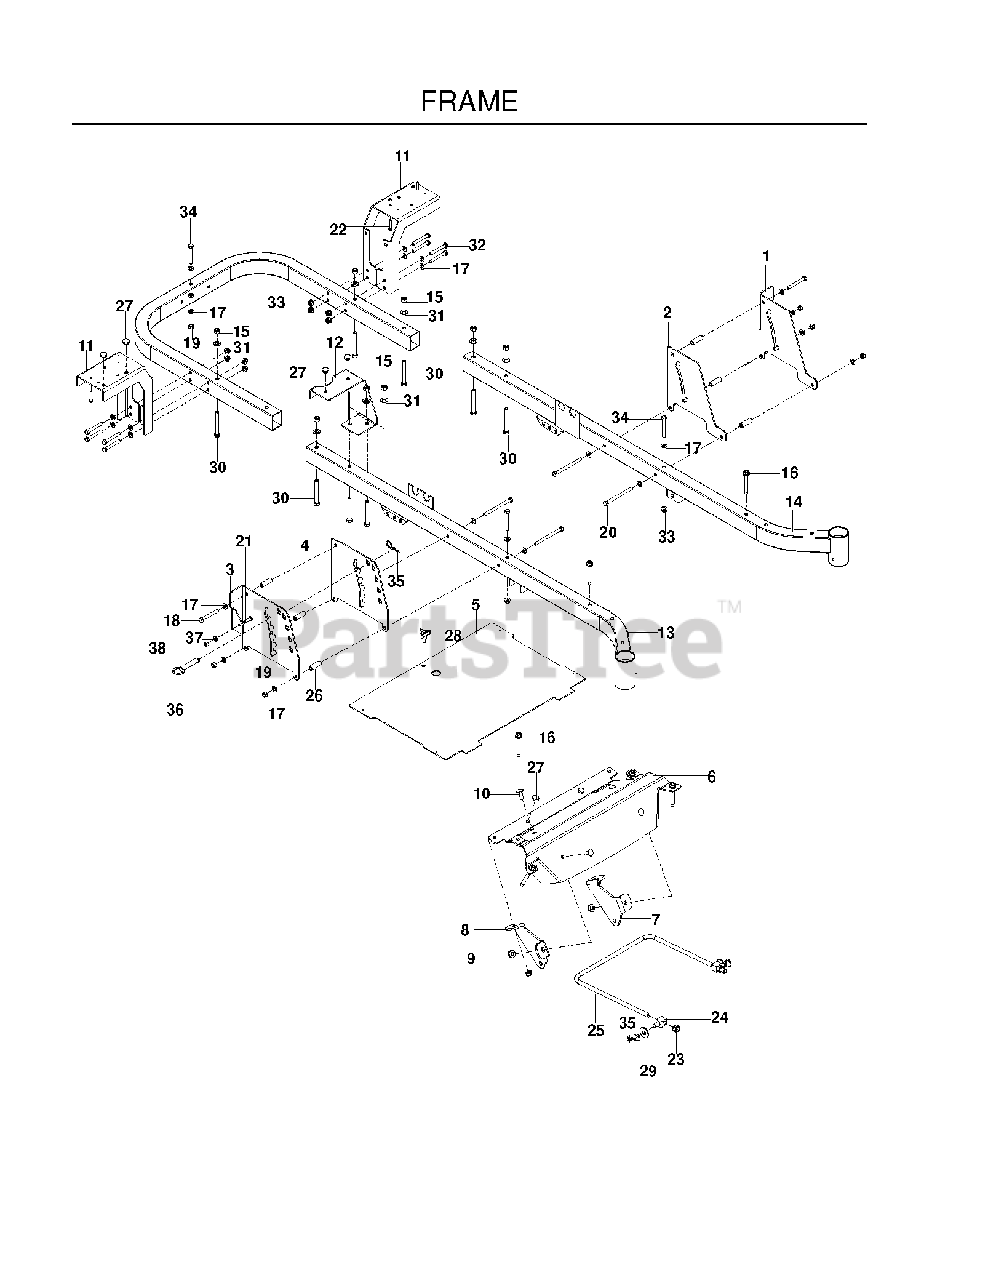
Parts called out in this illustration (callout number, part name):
1	PLATE, OUTER BRAKE, BLACK
2	PLATE, BRAKE LATCH, BLACK
3	PLATE, HEIGHT ADJ, BLACK
4	PLATE, DECK HEIGHT, BLACK
5	PLATE, FOOT W/DECALS RZ
6	FOOT.REST.MED.ORANGE
7	MOUNT, STRUT, RT, BLK
8	MOUNT, STRUT, LT, BLK
9	NUT 3/8-16 HEX FLG NYLOC ZD
10	RHSNB 3/8C X 1
11	SUPPORT, FENDER, BLACK
12	SUPPORT, TANK, BLACK
13	FRAME, RT, ORANGE
14	FRAME, LT, ORANGE
15	NUT 3/8-16 NYLOC
16	ENGINE BOLT, SPECIAL
17	FLAT WASHER 5/16 SAE
18	BOLT 5/16C X 2 1/2
19	NUT 5/16 NYLOC
20	HCS 5/16C X 4
21	HCS 1/4C X 1
22	SCR #10-12X1-1/2HEX WASH HD ZD
23	7/16-14 HEX NUT W/NYL RING ZD
25	LINK, FRONT SUSP.
26	SPACER, .334 ID X .5 OD X 1.5
27	GROMMET, BUMPER
28	KNOB W/STUD
29	WASH USS FLAT 1/2
30	HCS 3/8C X 3
31	WASHER 3/8 SAE FLAT
33	5/16-18 NYLOC FLANGE NUT
34	HCS 5/16C X 2-3/4
35	HAIRPIN #4
37	WASHER 1/4 SAE
38	RP_NUT 1/4-20 NYLOC
